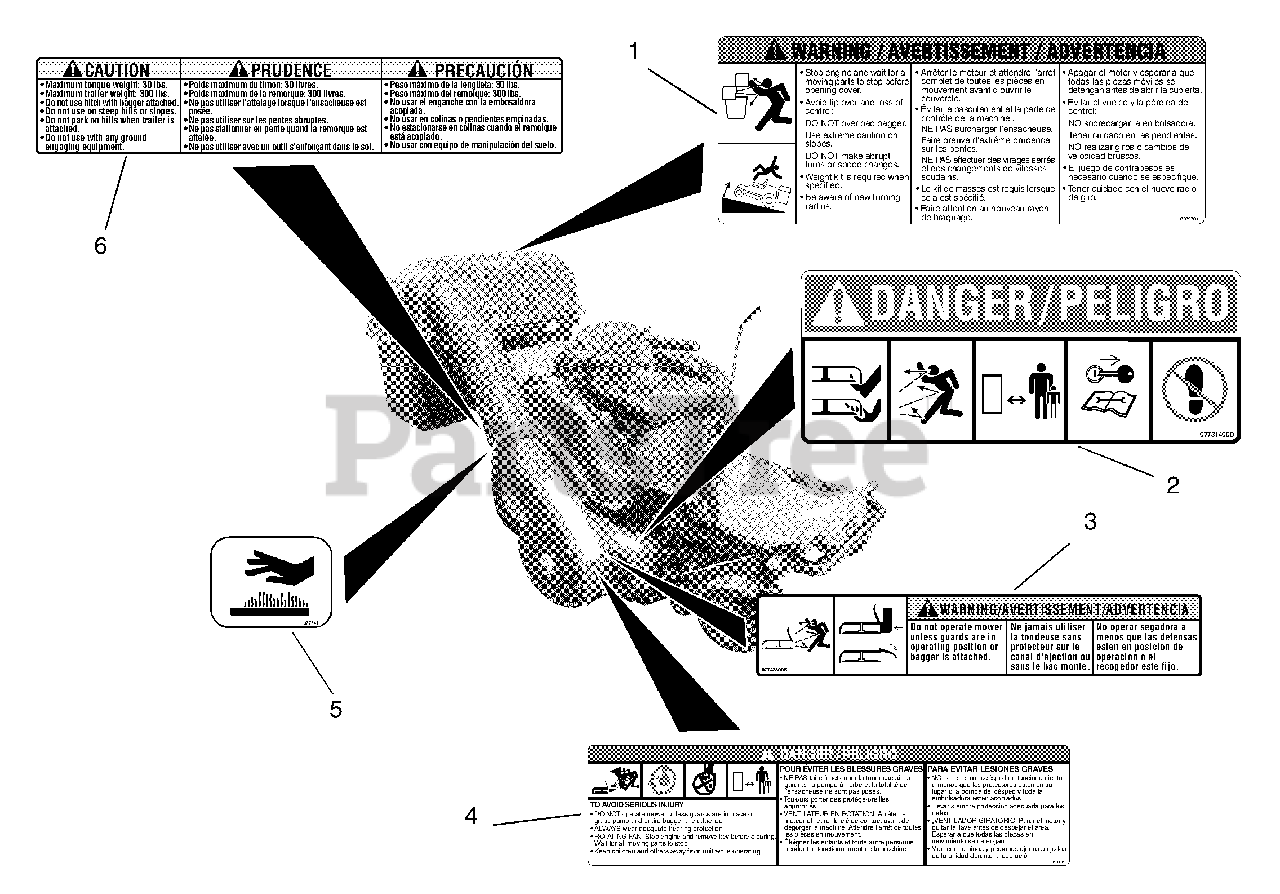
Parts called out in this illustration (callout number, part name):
1	DECAL, BAGGER COVER
2	DECAL, MOWER PAN DANGER
3	DECAL, WARNING
4	DECAL-CAUTION, GRASS PUMP
5	DECAL, HOT SURFACE
6	DECAL, TRAILER HITCH
